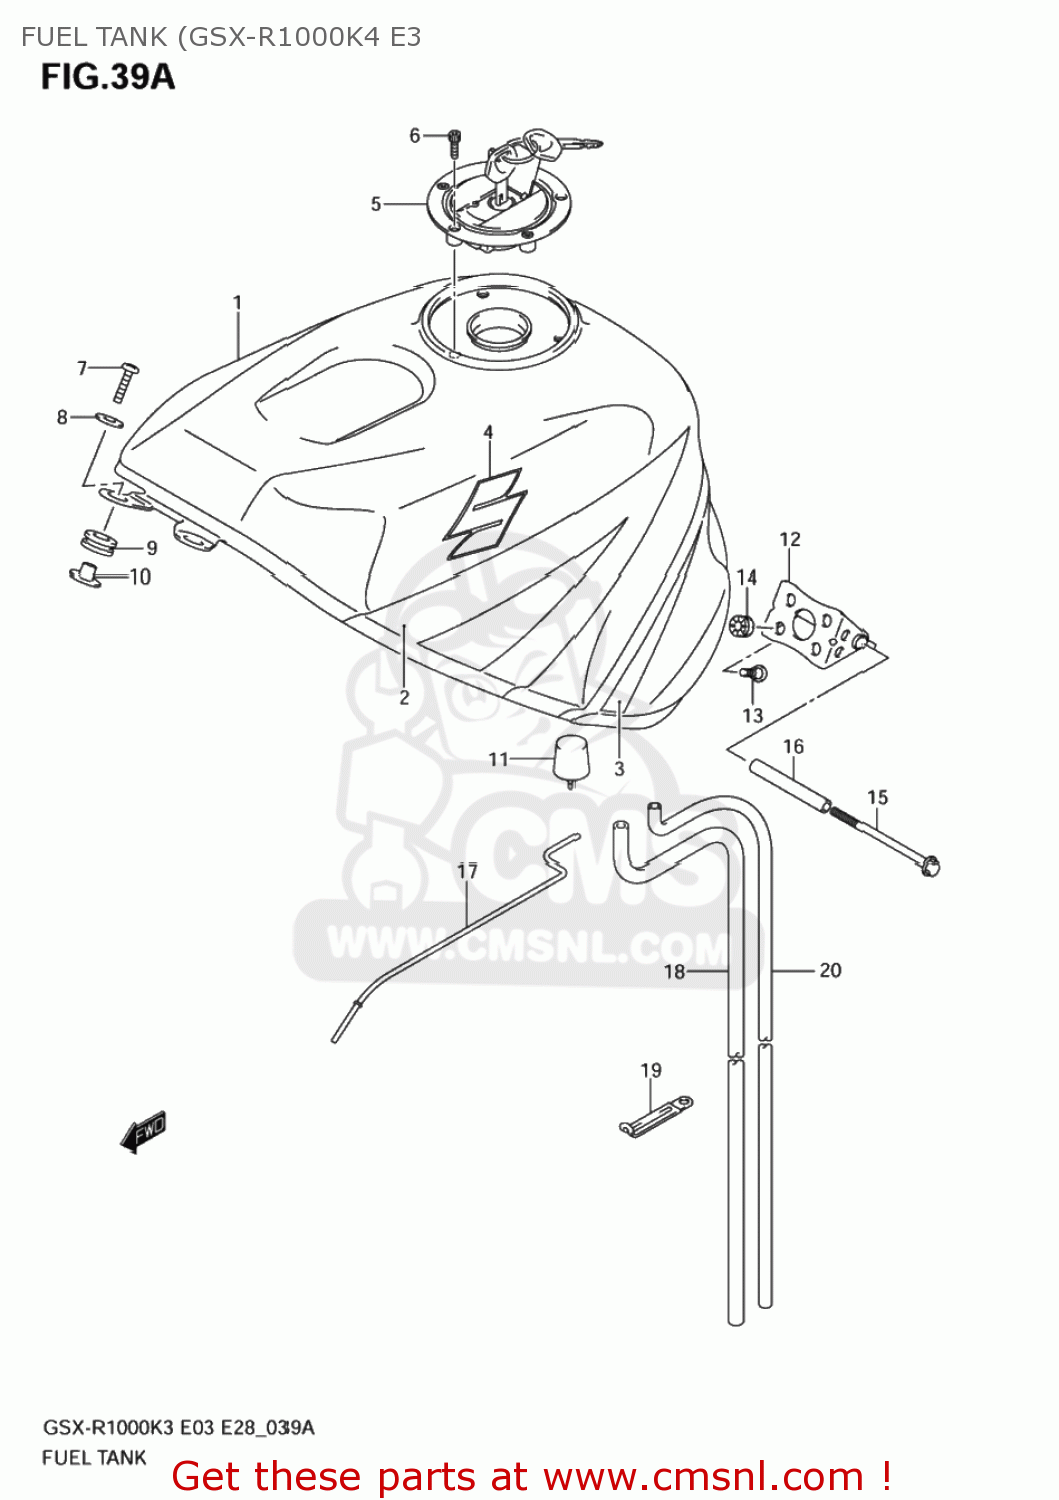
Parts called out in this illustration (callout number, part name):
1	TANK ASSY,FUEL(BLACK)
2	TAPE SET,FUEL TANK UPR
3	TAPE SET,TANK LWR
4	EMBLEM,FUEL TA
5	CAP SET,FUEL TANK
6	BOLT(5X20)
7	SCREW(6X25)
8	WASHER(6.5X22X1.6)
9	CUSHION,FUEL TANK FR
10	SPACER,FUEL TANK FR
11	CUSHION,FUEL TANK RR
12	BRACKET,FUEL TANK NO.1
13	SCREW,FUEL TAN
14	CUSHION
15	BOLT(6X110)
16	SPACER,FUEL TANK RR
17	STAY,FUEL TANK
18	HOSE,WATER DRAIN
19	CLAMP(L:65)
20	HOSE,FUEL TANK
